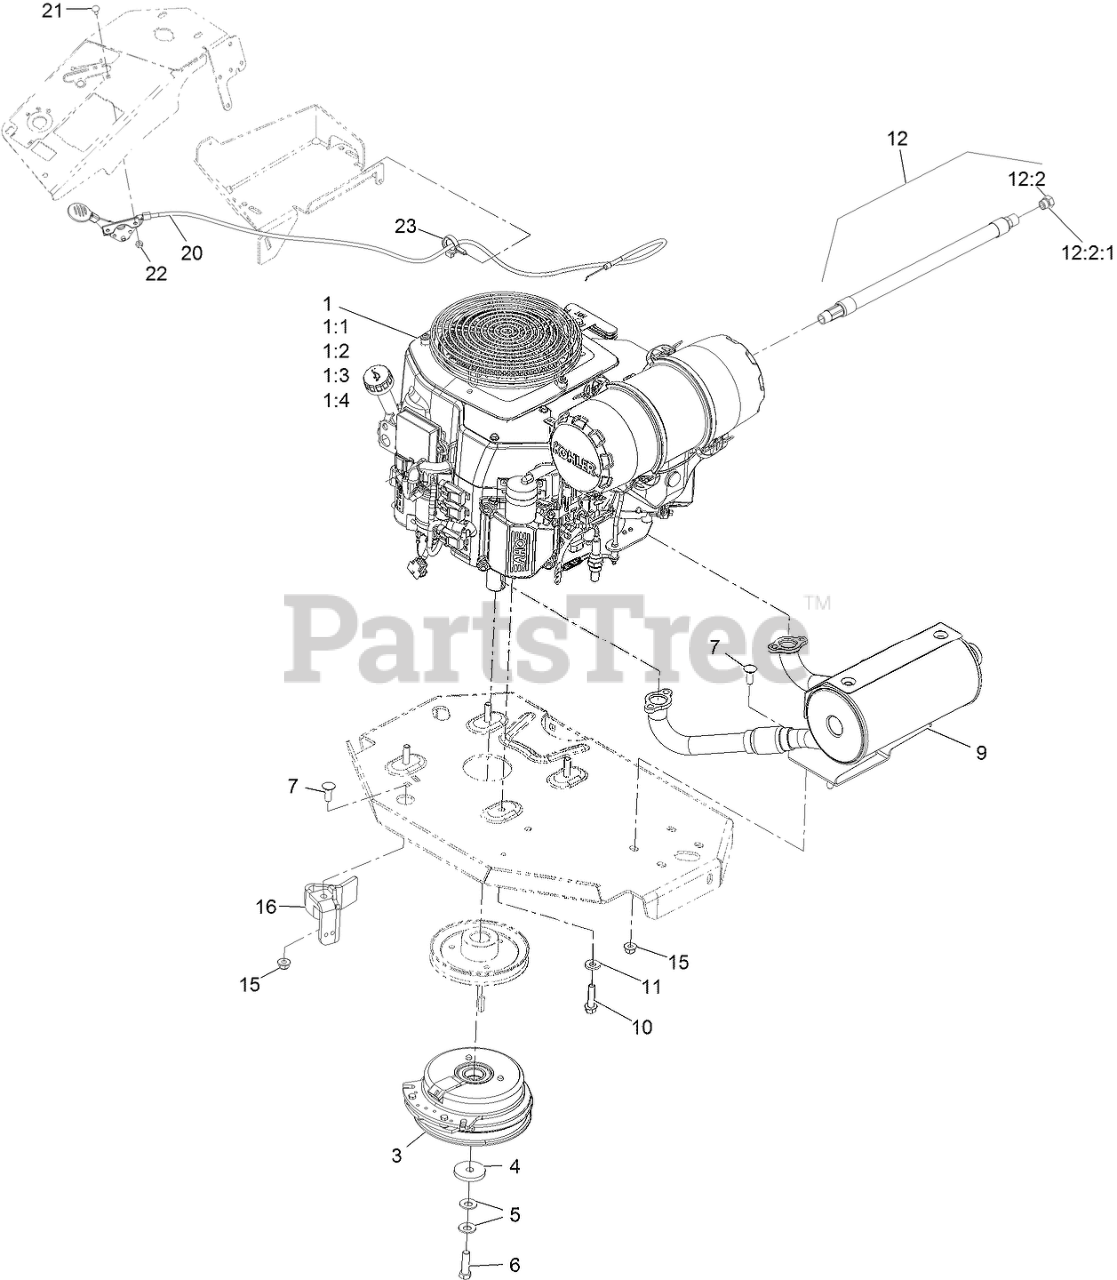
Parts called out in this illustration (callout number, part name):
1:1	Kohler 52 050 02-S Engine Oil Filter
1:2	Kohler 25 083 01-S Engine Air Filter
1:3	Kohler 25 083 04-S Safety Filter
1:4	Kohler 25 050 50-S Propane Fuel Filter
3	CLUTCH KIT
4	WASHER-CLUTCH
5	WASHER-SPRING
6	SCREW-HH 7/16-20 X 1 1/2 W/LOCTITE
7	SCREW-CARR
9	KIT,MUFFLER
10	SCREW-HWH
11	WASHER-BELLEVILLE
12	OIL DRAIN HOSE ASM
12:2	PLUG-HH
12:2:1	O-RING
15	NUT-HF, NI
16	CLUTCH-ANCHOR
20	ASM,THROTTLE CABLE
21	BOLT-CARR
22	NUT-LOCK, NI
23	CLAMP-HOSE
